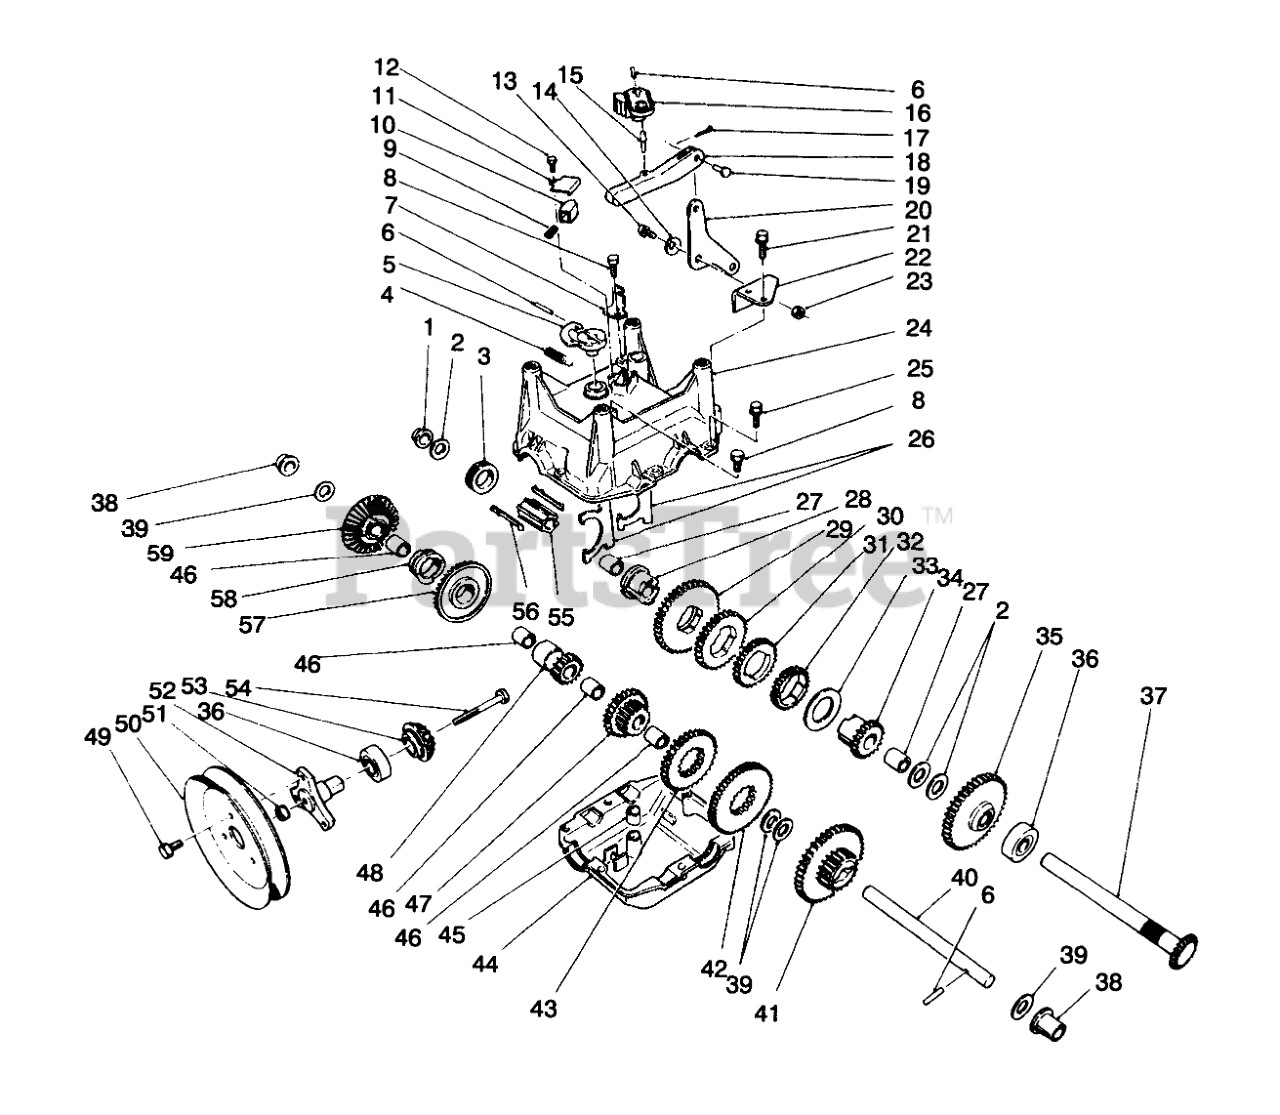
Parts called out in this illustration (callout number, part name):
1	BUSHING-FLANGE, OUTPUT
2	BEARING-THRUST
3	COLLAR-SHIFT
4	SPRING-EXTENSION
5	LEVER
6	PIN-SPRING
7	BRACKET-CABLE
8	SCREW-HWH
9	SPRING-DETENT
10	BUTTON-DETENT
11	COVER-DETENT
12	SCREW-HWH
13	SCREW-SHOULDER
14	WASHER-CURVED
15	PIN-LINK, GEAR SHIFT
16	LEVER-SHIFT, GEAR
17	PIN-COTTER
18	LINK-SHIFT, GEAR
19	PIN-CLEVIS
20	BELLCRANK
21	SCREW-HWH
22	BRACKET-BELLCRANK
23	NUT-LOCK, NI
24	GEARCASE-UPPER, CASING
25	SCREW-HWHTF
26	YOKE-SHIFT
27	BUSHING-OUTPUT
28	SLEEVE-GEAR
29	GEAR-45 T
30	GEAR-34 T
31	GEAR-27 T
32	GEAR-29 T
33	WASHER-THRUST
34	GEAR-SLEEVE, 19 T
35	GEAR-41 T
36	BEARING-BALL
37	SHAFT-OUTPUT
38	BUSHING-INTERMEDIATE
39	WASHER-THRUST
40	SHAFT-INTERMEDIATE
41	GEAR-19/41 T
42	GEAR-51 T
43	GEAR-33 T
44	GEARCASE-LOWER, CASING
45	BUSHING-YOKE
46	Bushing-Output
47	GEAR-26 T
48	GEAR-BEVEL, 15 T
49	SCREW
50	TRACTION-SHEAVE, HALF
51	NUT-HHF
52	HUB-PULLEY
53	PINION-BEVEL
54	SCREW-HH
55	SLEEVE-SHIFT
56	KEY-SHIFT
57	GEAR-BEVEL, 36 T
58	COLLAR-SHIFT
59	Gear-Bevel Reverse 36T (Incl. Ref. #46)
